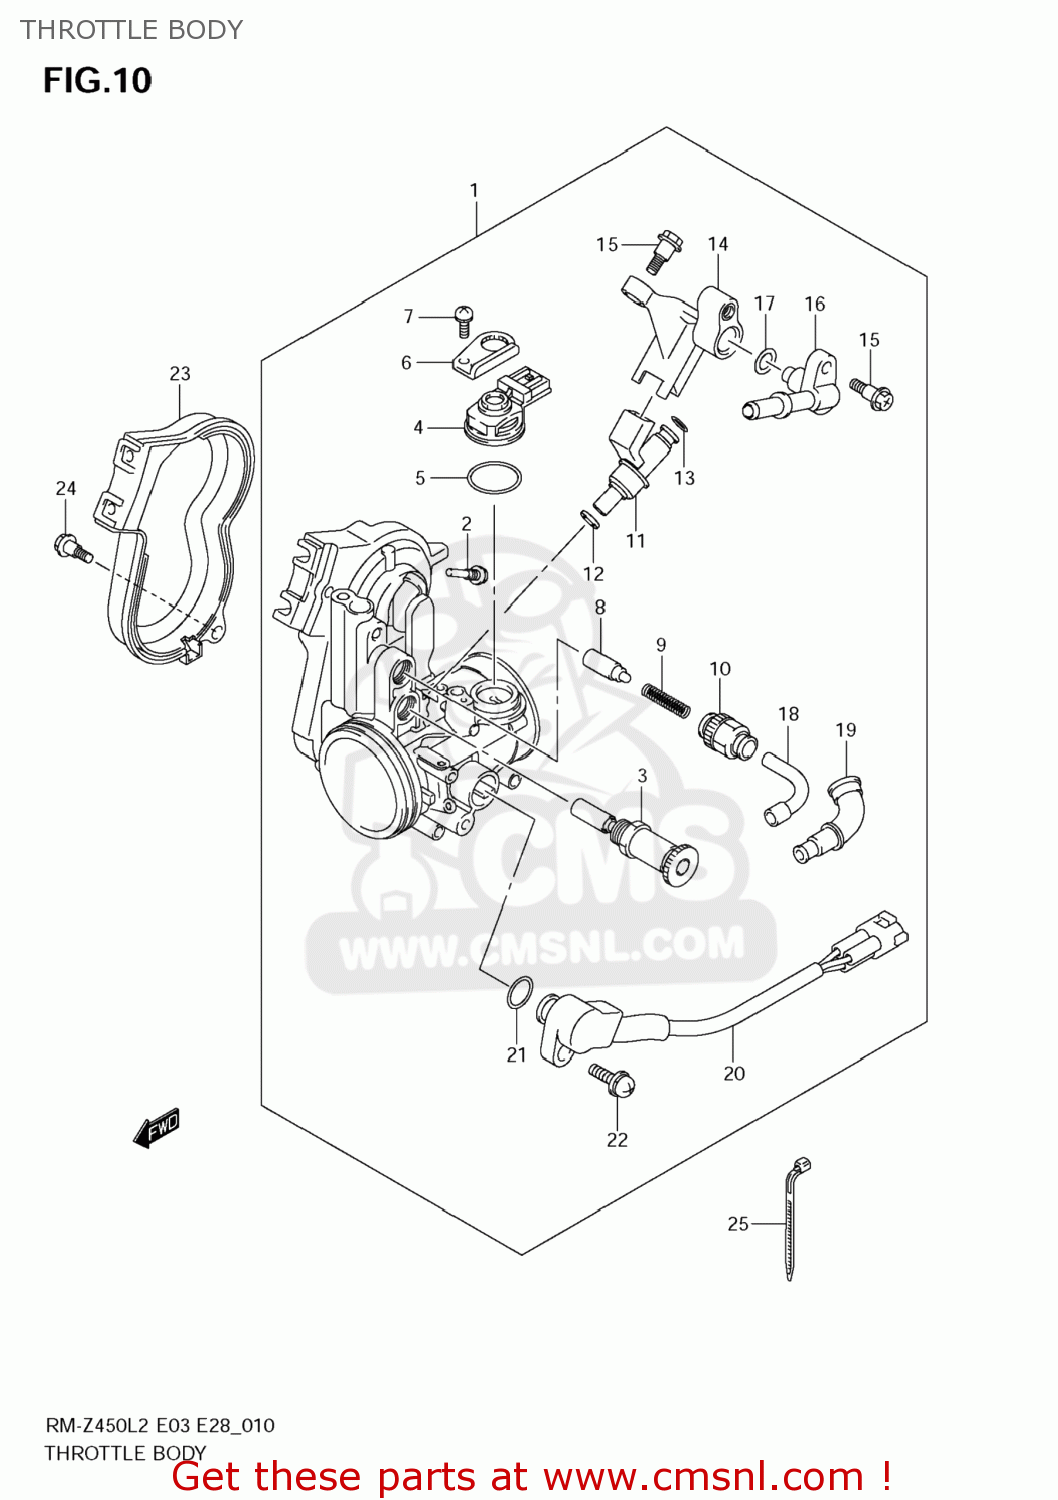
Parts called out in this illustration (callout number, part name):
1	BODY ASSY.THROT
2	SCREW
3	STARTER
4	SENSOR,MAP
5	O RING
6	PLATE,STAY
7	SCREW
8	VALVE,STARTER
9	SPRING
10	HOLDER,CABLE
11	INJECTOR ASSY
12	RING,SEAL
13	O RING
14	PIPE,FUEL
15	SCREW
16	JOINT
17	O RING
18	GUIDE,CABLE
19	CAP
20	SENSOR ASSY,THROTTLE
21	O RING
22	SCREW
23	COVER
24	SCREW
25	CLAMP(L:95)
